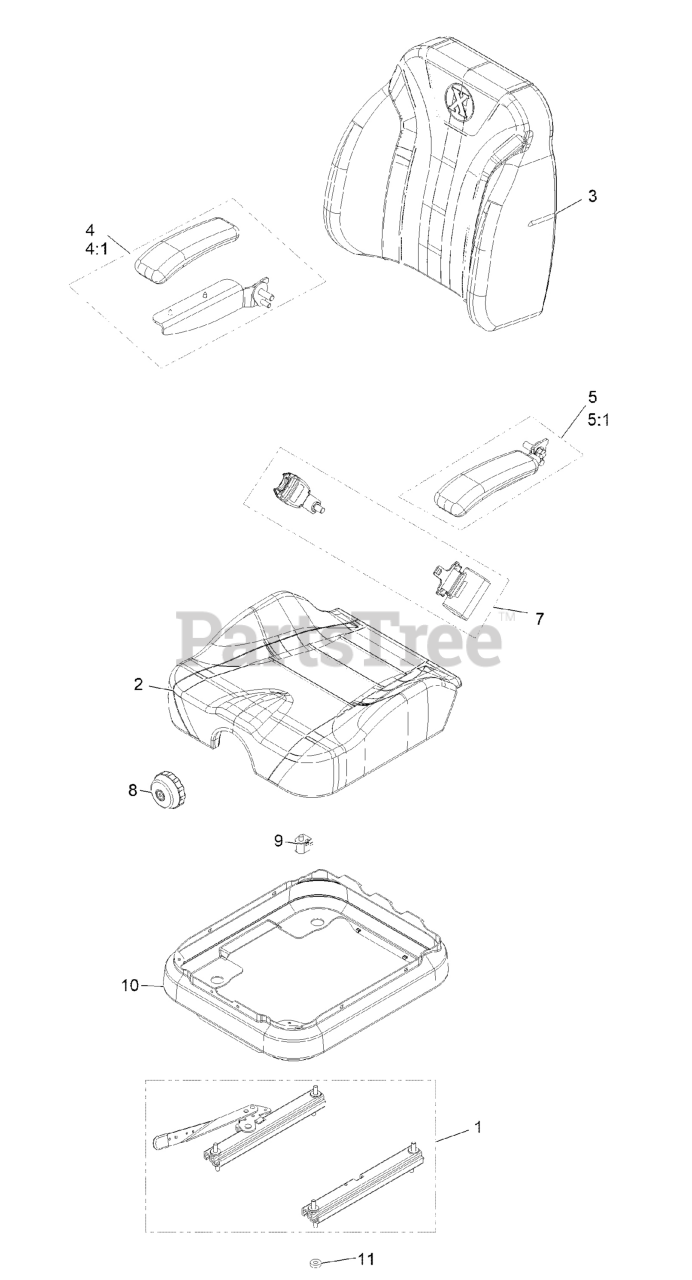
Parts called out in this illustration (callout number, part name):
1	TRACKS-4" TRAVEL
2	COVER, LOWER
3	COVER, UPPER
4	RH Arm Rest Kit
4:1	CUSHION-REST, ARM
5	LH Arm Rest Kit
5:1	CUSHION-REST, ARM
7	KIT-SEAT BELT
8	KNOB-ADJUSTER
9	SWITCH-BAIL
10	BELLOWS-SEAT
